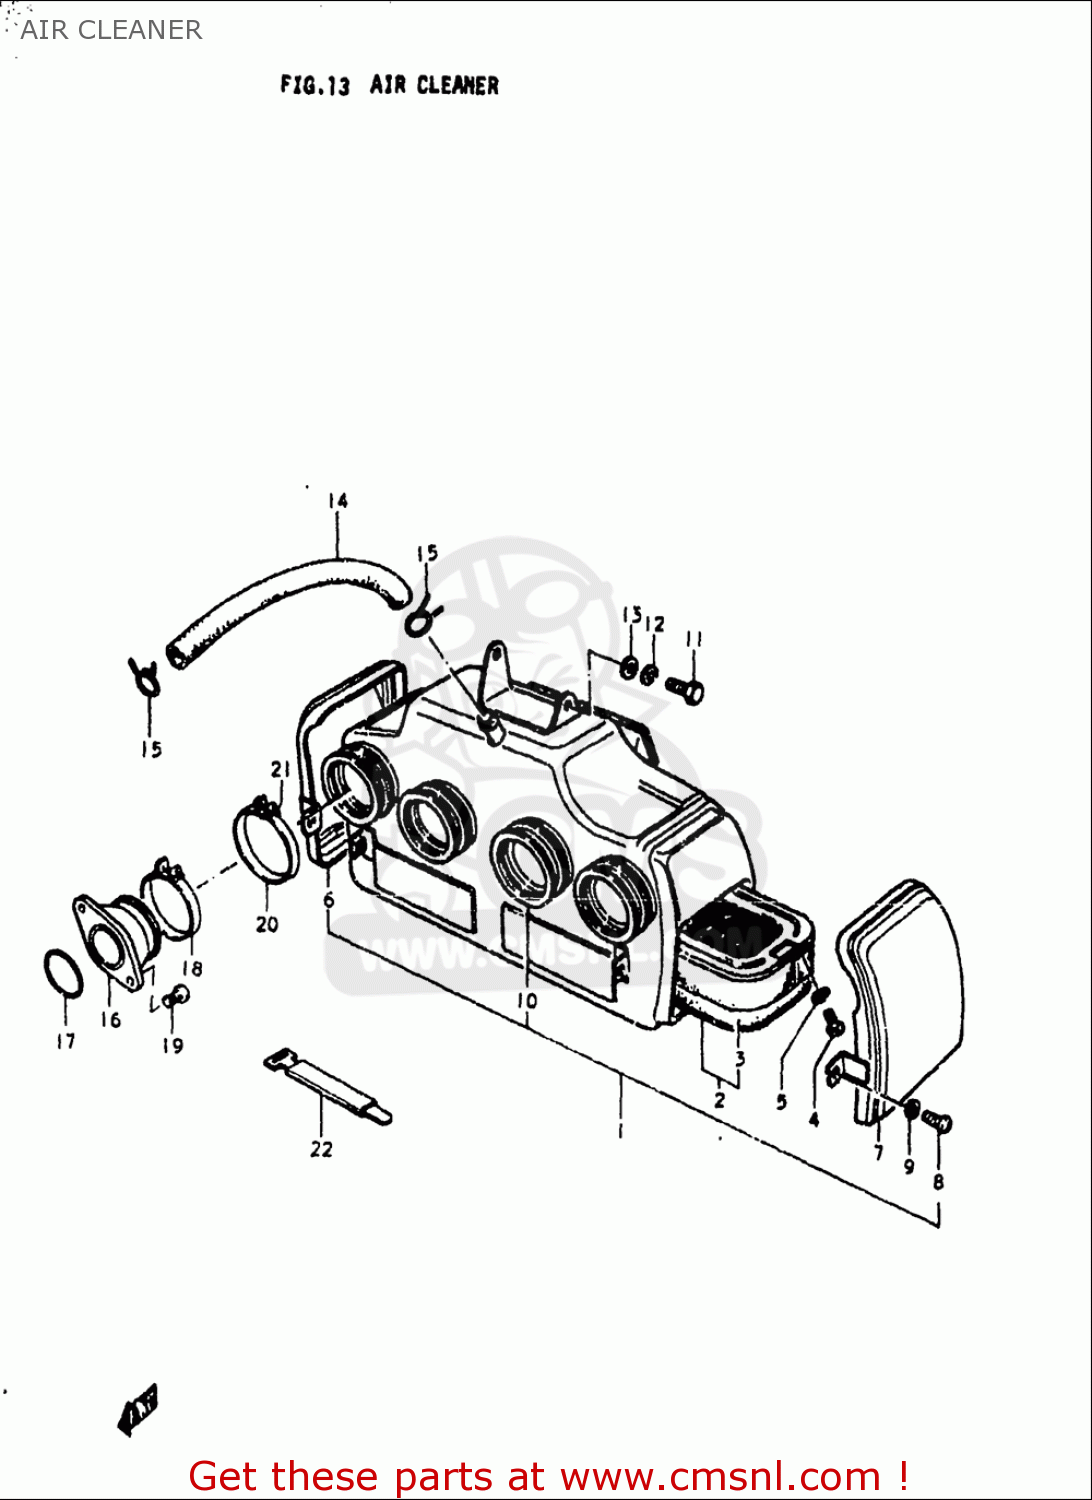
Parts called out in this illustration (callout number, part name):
1	CLEANER ASSEMBLY,AIR
2	FILTER ASSY,AIR CLEANER
3	FILTER
4	SCREW
5	WASHER,LOCK
6	CAP,AIR CLEANER,R
7	CAP,L
8	SCREW
9	WASHER,LOCK
10	HOSE
11	BOLT
12	WASHER,LOCK
13	WASHER
14	HOSE(11X15X2000)
15	CLIP
16	PIPE,INTAKE
17	O RING(D:2.4,ID:31.7)
18	CLAMP
19	SCREW
20	CLAMP
21	SCREW
22	CLAMP(L:120)
